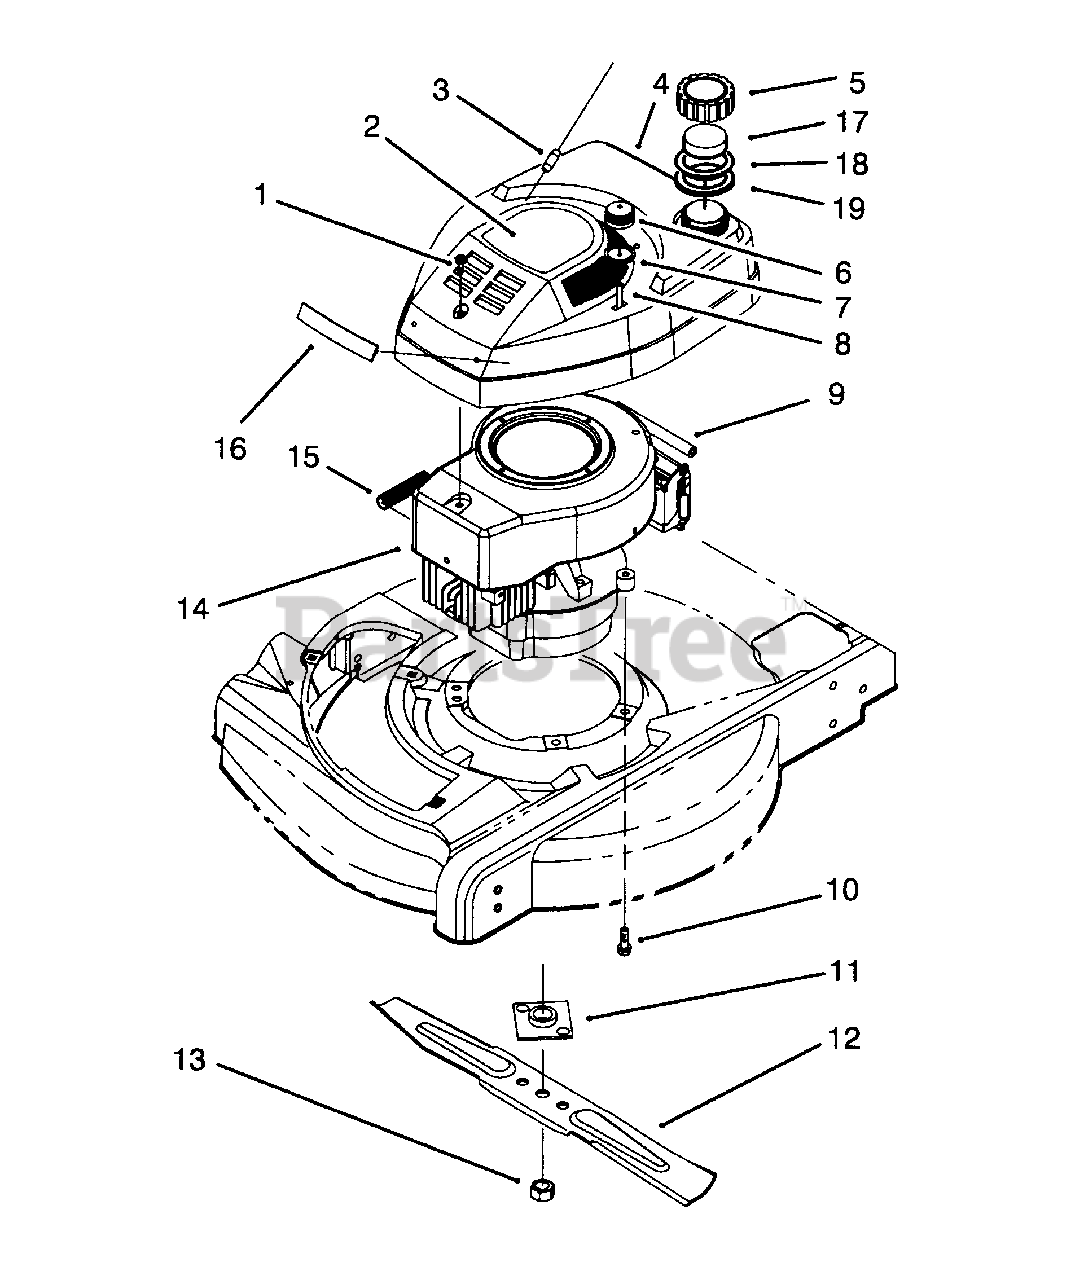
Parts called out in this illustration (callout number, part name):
1	Screw-Sems
2	Decal-Shroud
3	Rope-Stop
4	Tank & Shroud Assembly
5	Gas Cap Assembly (Incl. Ref. #17-19)
6	Bulb-Primer
7	Body-Primer
8	Hose-Primer
9	Line-Gas
10	Screw-Engine
11	Plate & Collar Assembly
12	Blade-21"
13	Nut-Blade
14	Engine
15	Spring-Compression
16	Applique-Shroud
